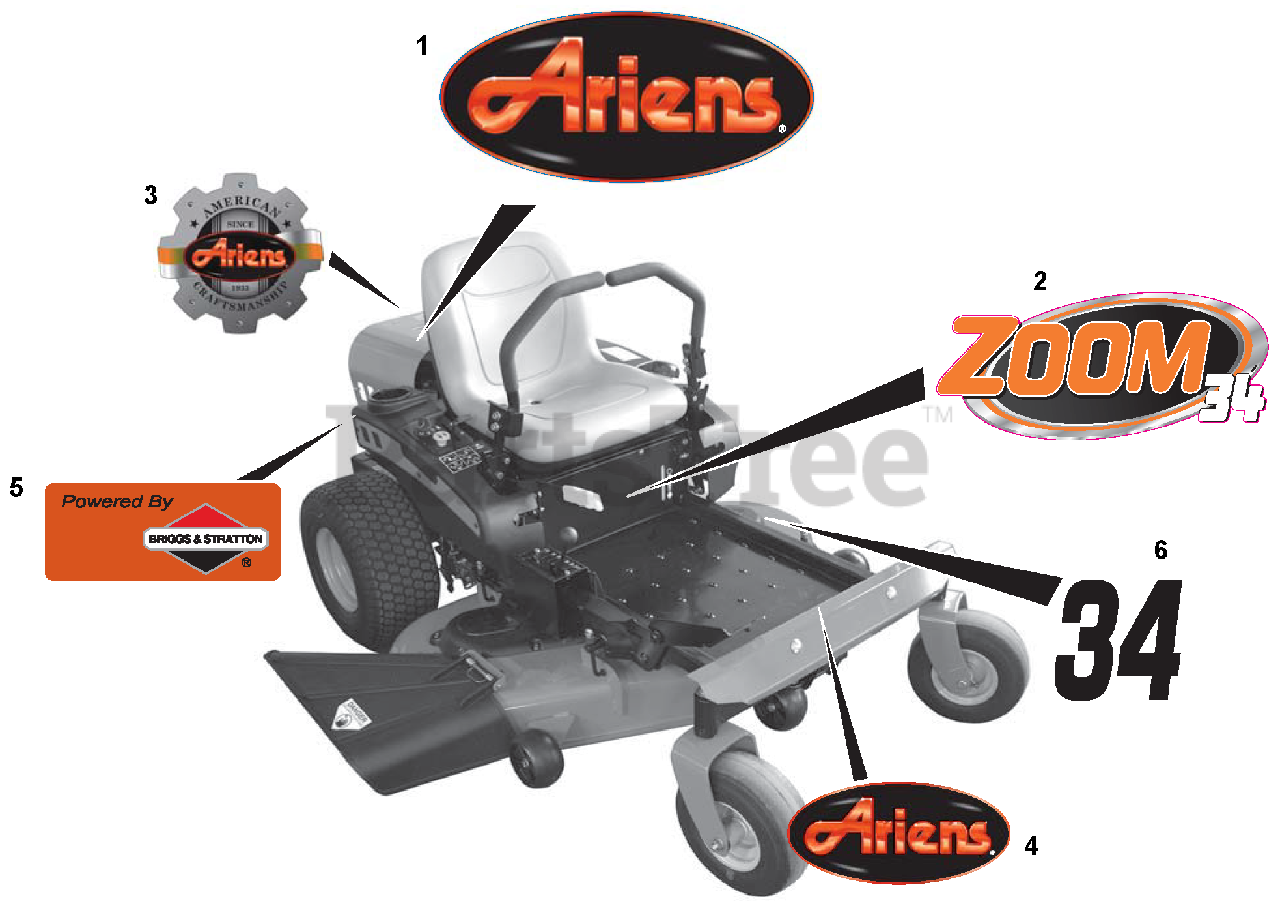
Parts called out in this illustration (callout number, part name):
1	DECAL, ARIENS JEWEL
2	DECAL, ZOOM 34
3	Decal, Ariens Heritage, Large
4	DECAL, ARIENS JEWEL
5	DECAL, POWERED BY B&S
6	DECAL, DECK SIZE, 34"
